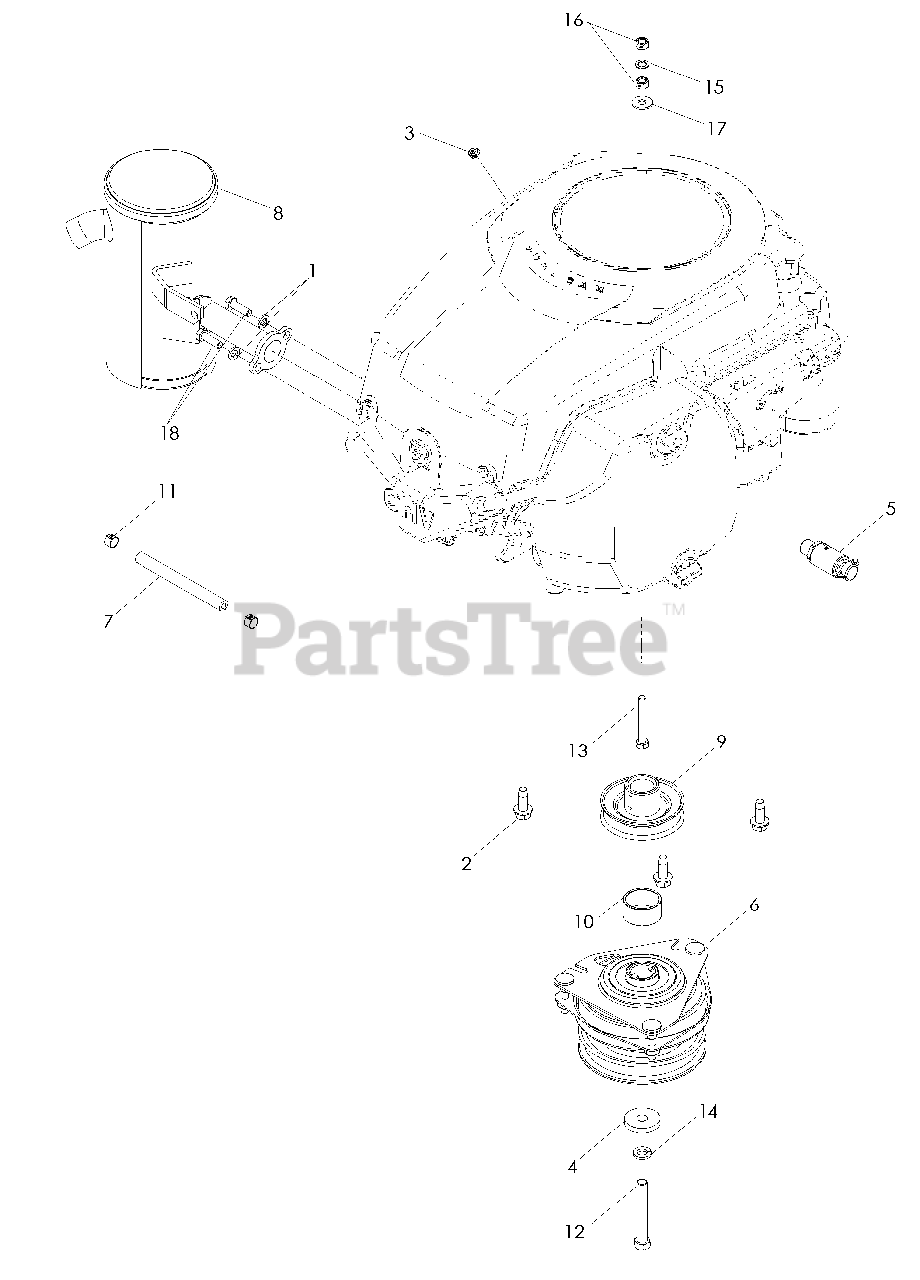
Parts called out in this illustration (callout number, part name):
1	WASHER 5/16 SLW
2	BOLT, 3/8-16 x 1, THD FRM
3	NUT, 1/4-20, THIN, NYLOC
4	CLUTCH WASHER
5	OIL DRAIN FITTING
6	CLUTCH
7	FUEL LINE, 5"
9	PULLEY, ENGINE
10	SPACER, ENGINE PULLEY
11	CLAMP, HOSE
12	HCS, 7/16-20 x 3
13	HCS 5/16-18 x 2 1/4
14	WASHER 7/16 SLW
15	WASHER 5/16 x 19/32
16	NUT 5/16-18 HEX CTRLK
17	WASHER, 5/16 STD FLT
18	HCS 5/16-18 x 1
